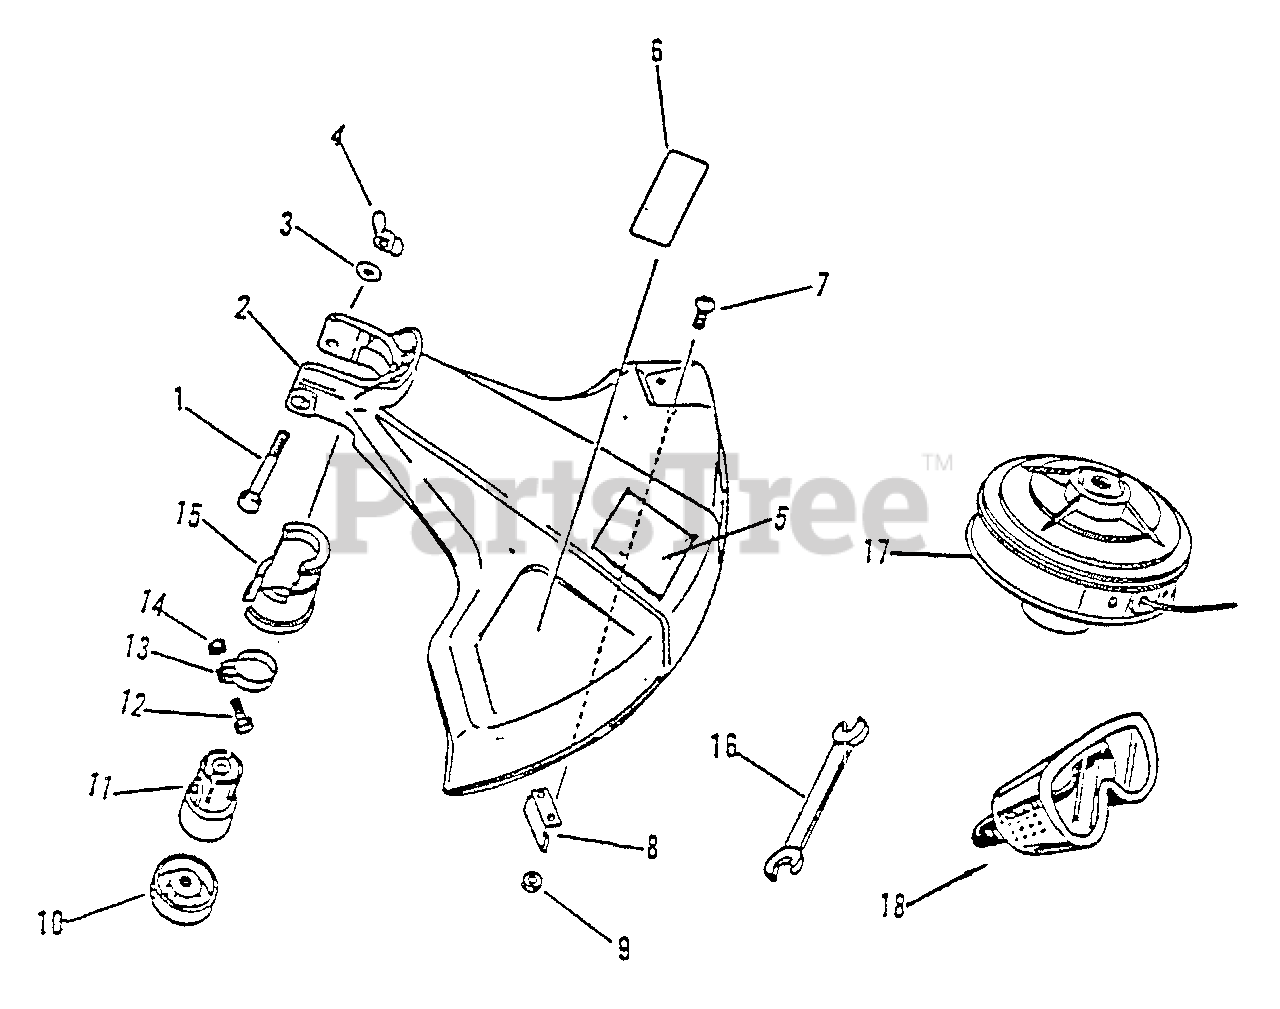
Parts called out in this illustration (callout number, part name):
1	BOLT - 6X50
2	SHIELD
3	WASHER - 6
4	WINGNUT - 6
5	LABEL - CAUTION
6	LABEL - ECHO
7	SCREW - 5X16
8	KNIFE, TRIMMER LINE
10	ADAPTOR, BLADE - UPPER
11	GEAR CASE ASSY
15	BRACKET, BEARING CASE
16	SPANNER - 8X10mm
17	GT ECHOMATIC HEAD
18	GOGGLES
